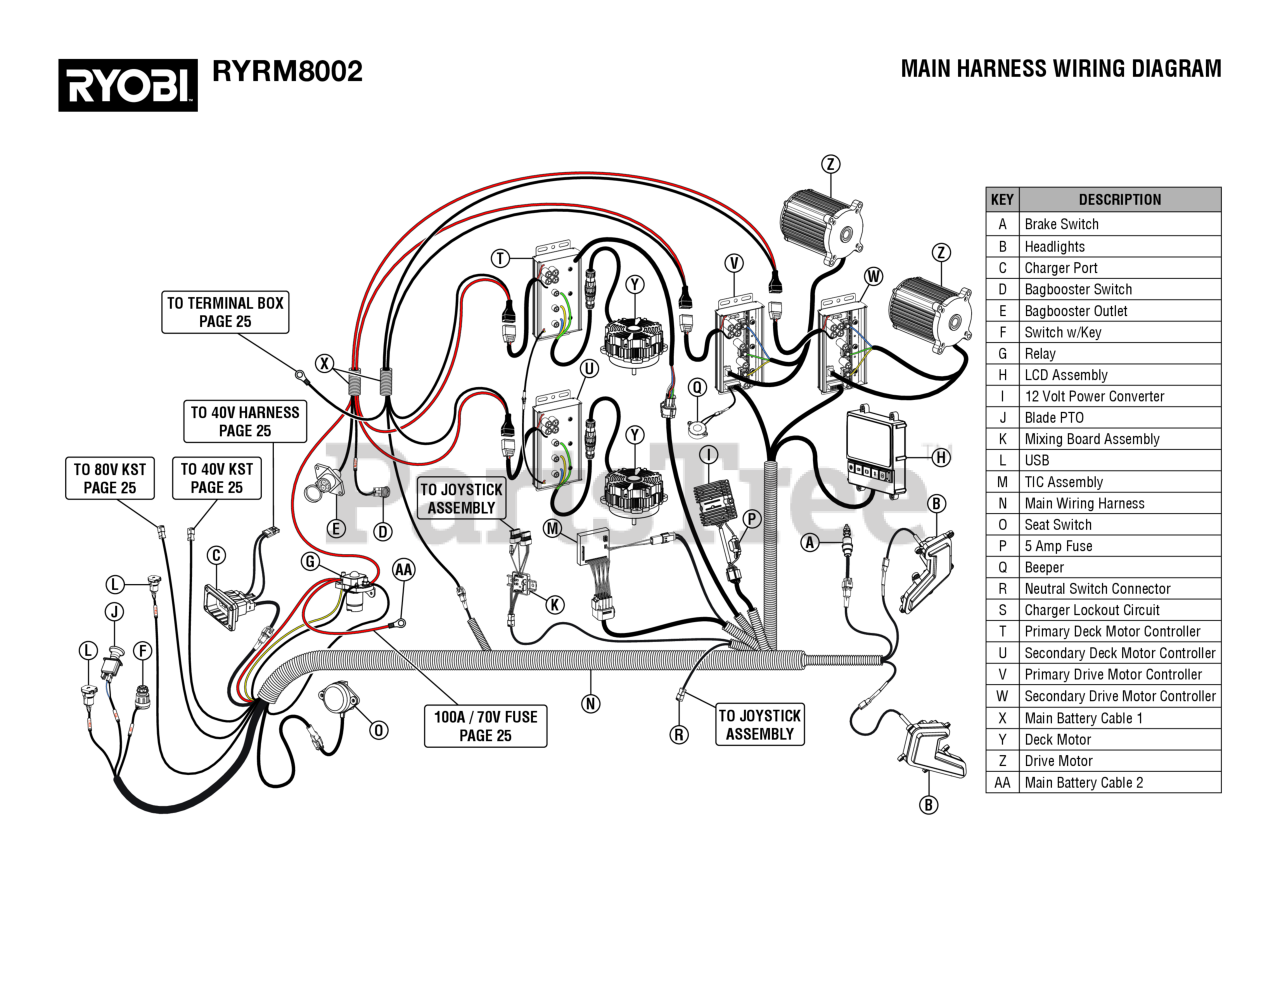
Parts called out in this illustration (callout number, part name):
A	Brake Switch
B	Headlights
C	Charger Port
D	Bagbooster Switch
E	Bagbooster Outlet
F	Switch w/Key
G	Relay
H	LCD Assembly
I	12 Volt Power Converter
J	Blade PTO
K	Mixing Board Assembly
L	USB
M	TIC Assembly
N	Main Wiring Harness
O	Seat Switch
P	5 Amp Fuse
Q	Beeper
R	Neutral Switch Connector
S	Charger Lockout Circuit
T	Primary Deck Motor Controller
U	Secondary Deck Motor Controller
V	Primary Drive Motor Controller
W	Secondary Drive Motor Controller
Y	Deck Motor
Z	Drive Motor
